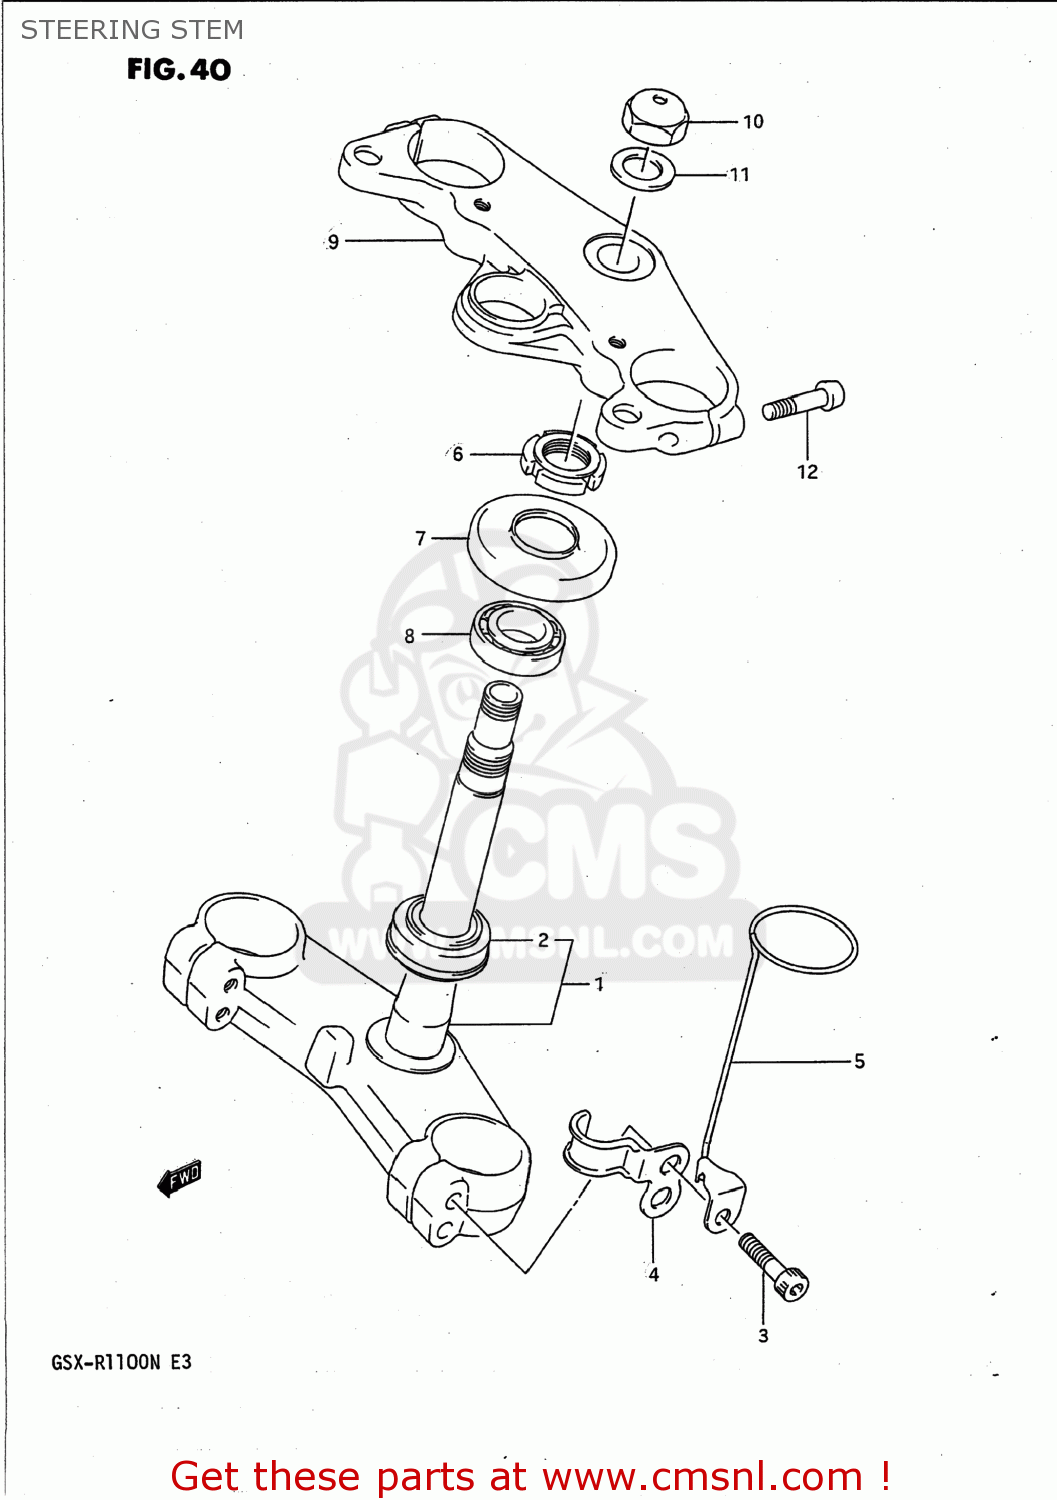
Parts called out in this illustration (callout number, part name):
1	STEM,STEERING
2	BEARING(30X55X17)
3	BOLT 10X45
4	GUIDE,SPEEDOMETER CABLE
5	HOLDER,STEERING DAMPER
6	NUT,STEERING STEM(25X44X10)
7	SEAL OIL
8	TAPER,ROLLER BEARING
9	HEAD,STEERING STEM
10	NUT
11	WASHER(22.5X32X1.6)
12	BOLT,LOWER
